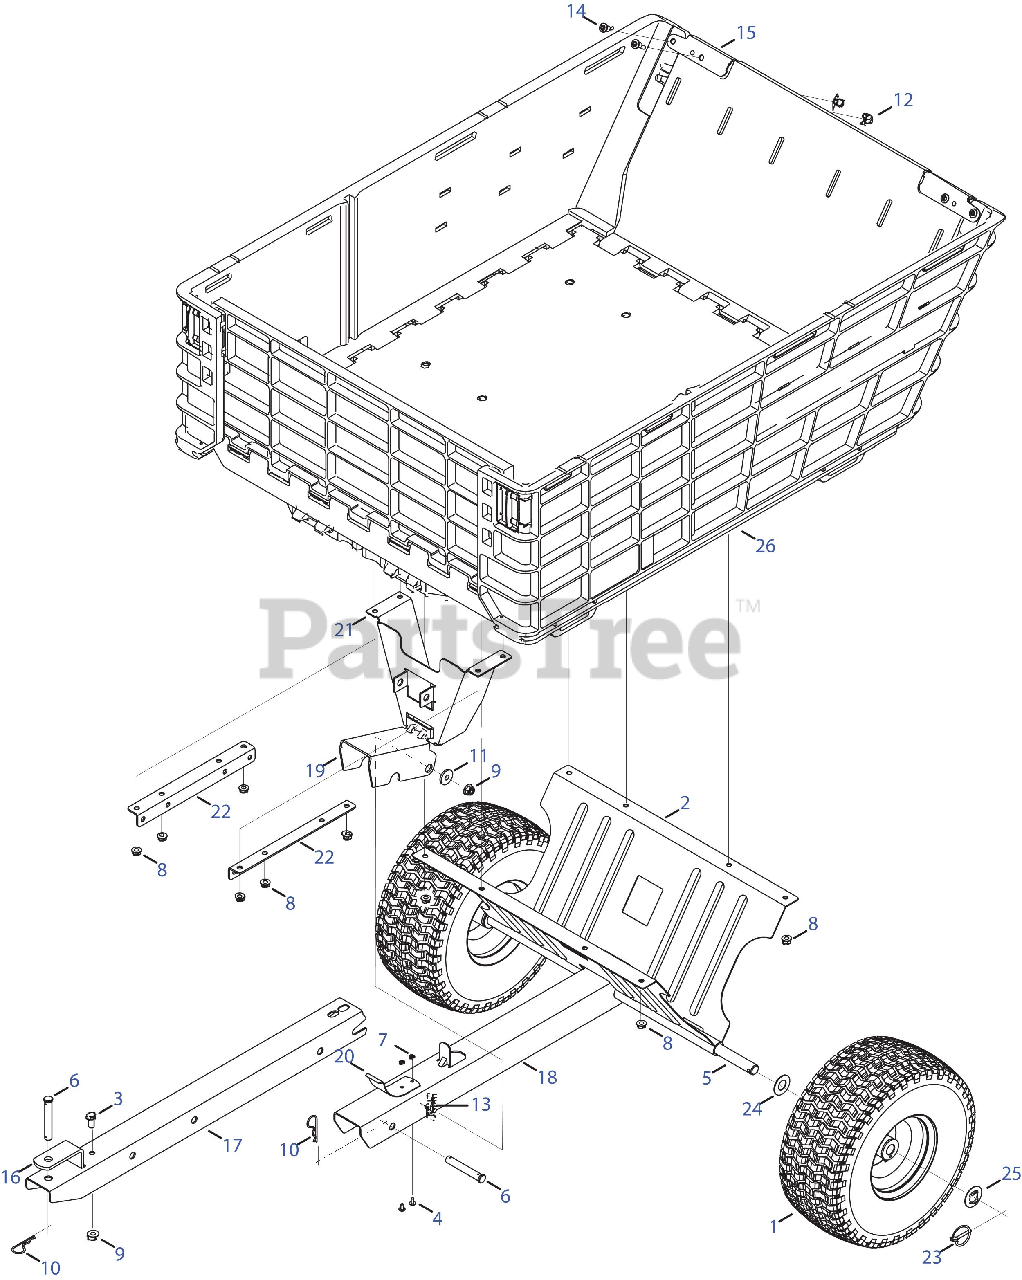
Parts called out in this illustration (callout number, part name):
1	Wheel Assembly, 15 x 6 x 6
3	Hex Screw, 3/8-16 x .75
4	Screw, 10-24 x .393
5	Axle Shaft, .750 x 29.88
6	Clevis Pin, .50 x 3.25
7	Hex Lock Nut, #10-24
8	Flange Lock Nut, 5/16-18
9	Flange Lock Nut, 3/8-16
10	Cotter Pin
11	Shoulder Spacer, .625 x .169
12	Shoulder Nut, .375 x .5
13	Shoulder Screw, 3/8-16 x .500 x 2.875
14	Shoulder Screw, 1/4-20 x .375 x .500
20	Pedal Release Spring
23	Lynch Pin, .1875
24	Flat Washer, .760 x 1.490 x .030
25	Flat Washer, .781 x 1.590
26	Bed Assembly
